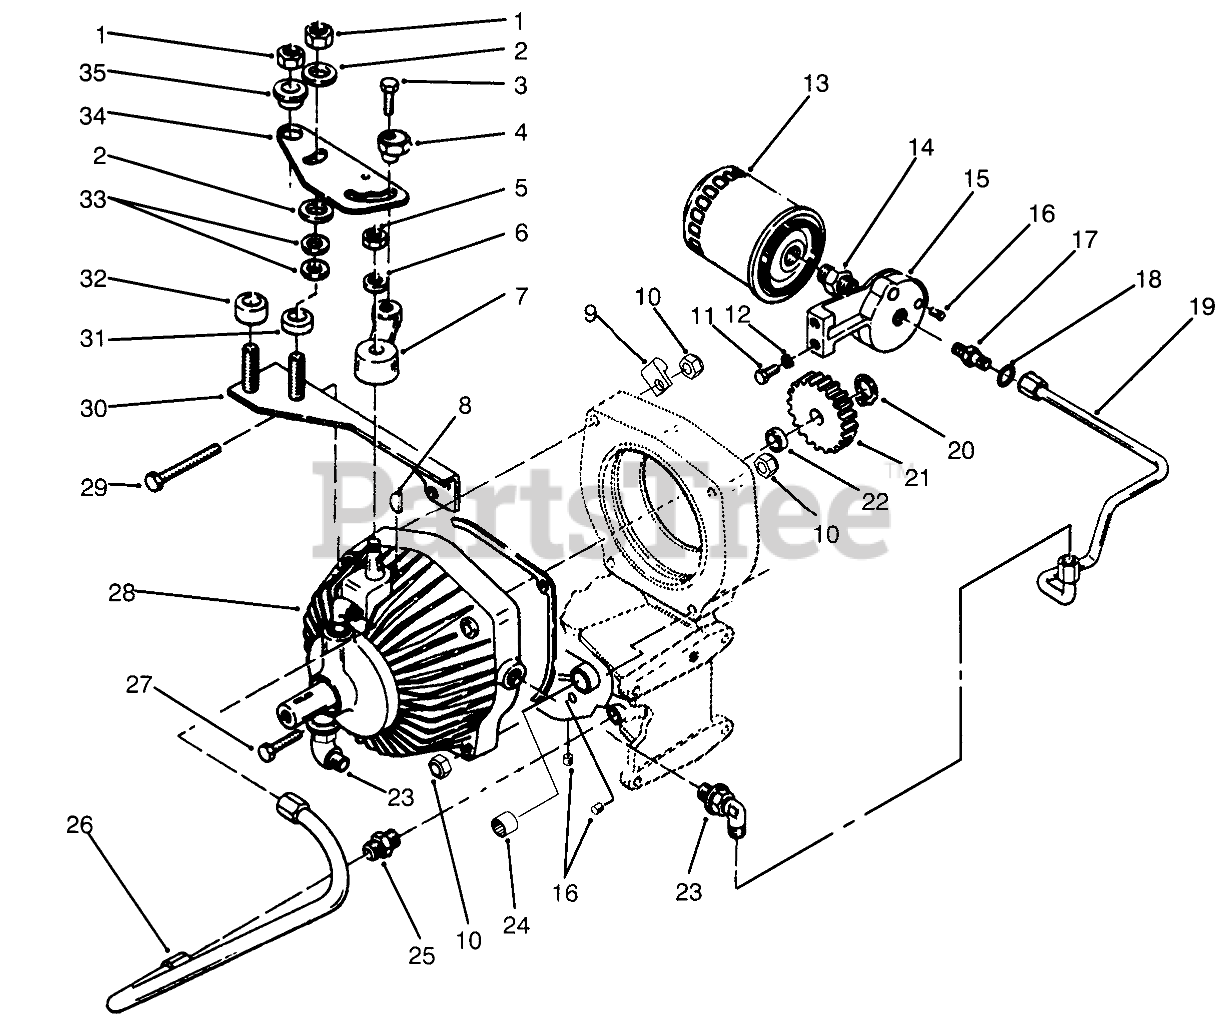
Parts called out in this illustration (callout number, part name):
2	FRICTION WASHER
3	Bolt
5	NUT-LOCK, NI
6	WASHER-FLAT
7	ARM-SPEED CONTROLB
8	KEY-WOODRUFF
9	CLIP
10	NUT-LOCK, NI
11	SCREW-HH
12	WASHER-LOCK
13	OIL FILTER ASM
14	FITTING
15	BASE-FILTER
17	FITTING
18	0-Ring
19	ASS'Y-TUBE FILTER
20	RING-SNAP, EXTERNAL
21	GEAR 20 TEETH DRIVE
22	SPACER GEAR
23	ELBOW
24	BEARING-NEEDLE
25	FITTING-TUBE
26	ASSY-TUBE SUCTION
27	Bolt
28	Pump & Motor
29	SCREW-HH
30	ASSY-PLATE B
31	SPACER-FRICTION
32	SPACER-PIVOT
33	WASHER-SPRING DISC
34	ASM-REAR LIFT R
35	CAM-SPACER
